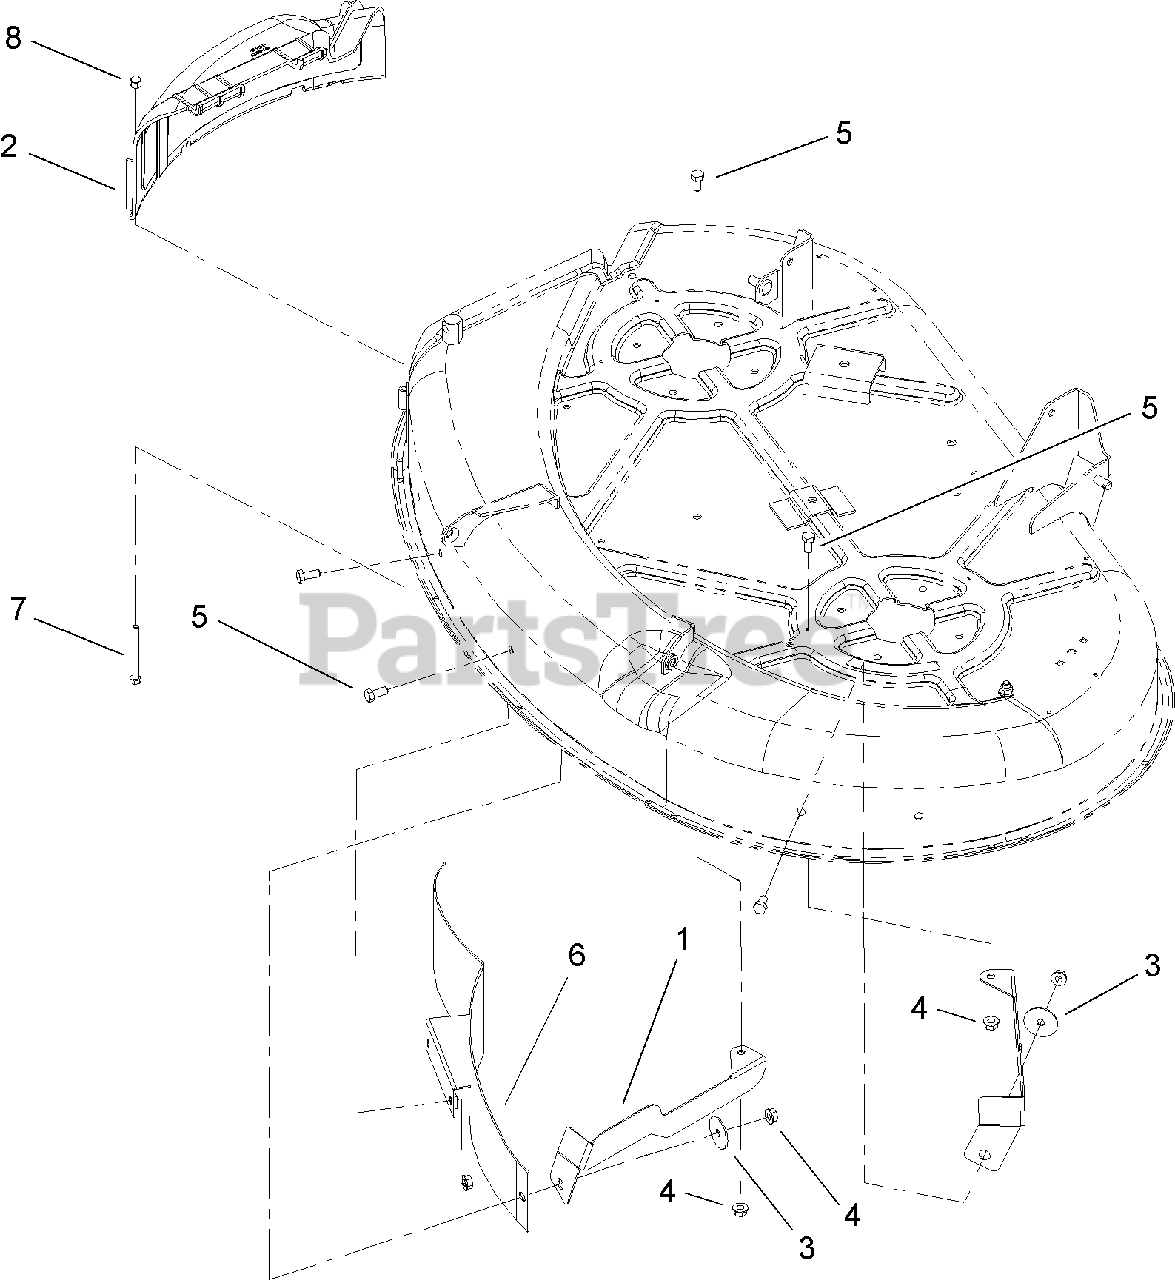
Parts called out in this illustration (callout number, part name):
1	BAFFLE-MULCH
2	COVER-DISCHARGE, DECK
3	WASHER-FLAT
5	SCREW-HH
6	BAFFLE-FRONT, RIGHT
7	SCREW-HH
